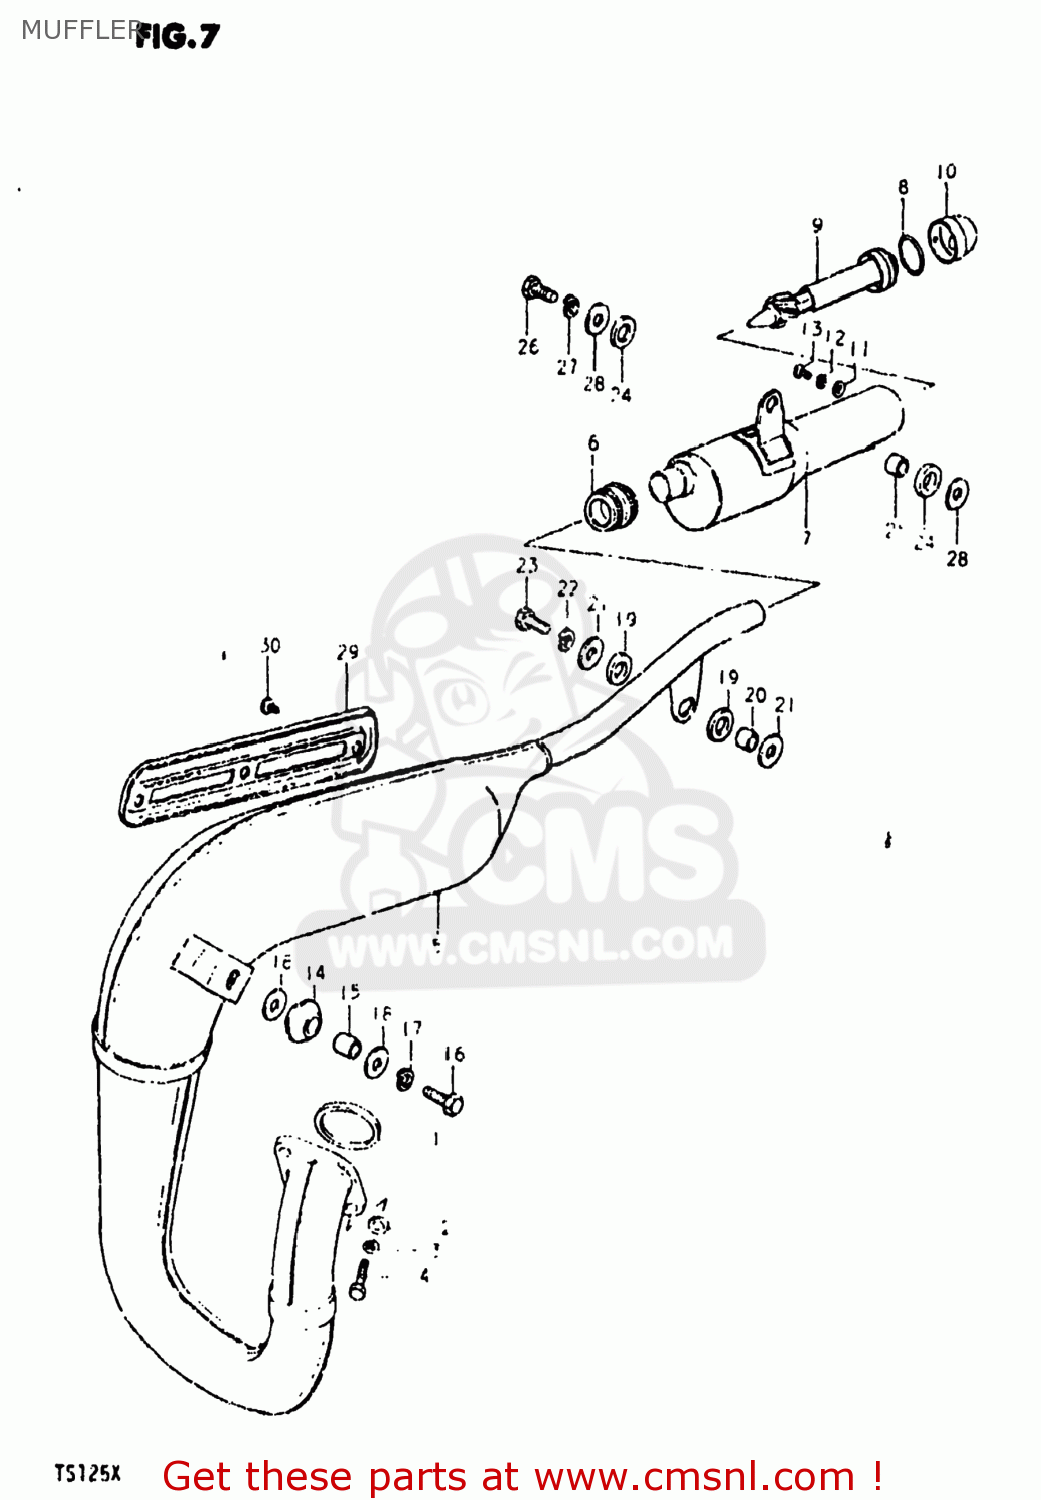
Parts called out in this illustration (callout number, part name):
1	GASKET,EXHAUST PIPE (NAS)
2	WASHER
3	LOCK WASHER
4	SCREW (6X25)
5	BODY,MUFFLER
6	CONNECTOR,MUFFLER
7	MUFFLER ASSEMBLY
8	O-RING (D:3.5 ID:54.4)
9	TUBE,MUFFLER CLEAN OUT
10	COVER,SECOND MUFFLER TAIL
11	SCREW(6X8)
12	LOCK WASHER
13	WASHER
14	DAMPER,MUFFLER,FR
15	SPACER (8X12X15)
16	BOLT
17	LOCK WASHER
18	WASHER (8.7X22X2)
19	CUSHION
20	SPACER (8.6X13.8X9.8)
21	WASHER
22	LOCK WASHER
23	BOLT
24	CUSHION
25	SPACER (8.6X13.8X9)
26	BOLT
27	LOCK WASHER
28	WASHER
29	COVER,MUFFLER
30	SCREW
